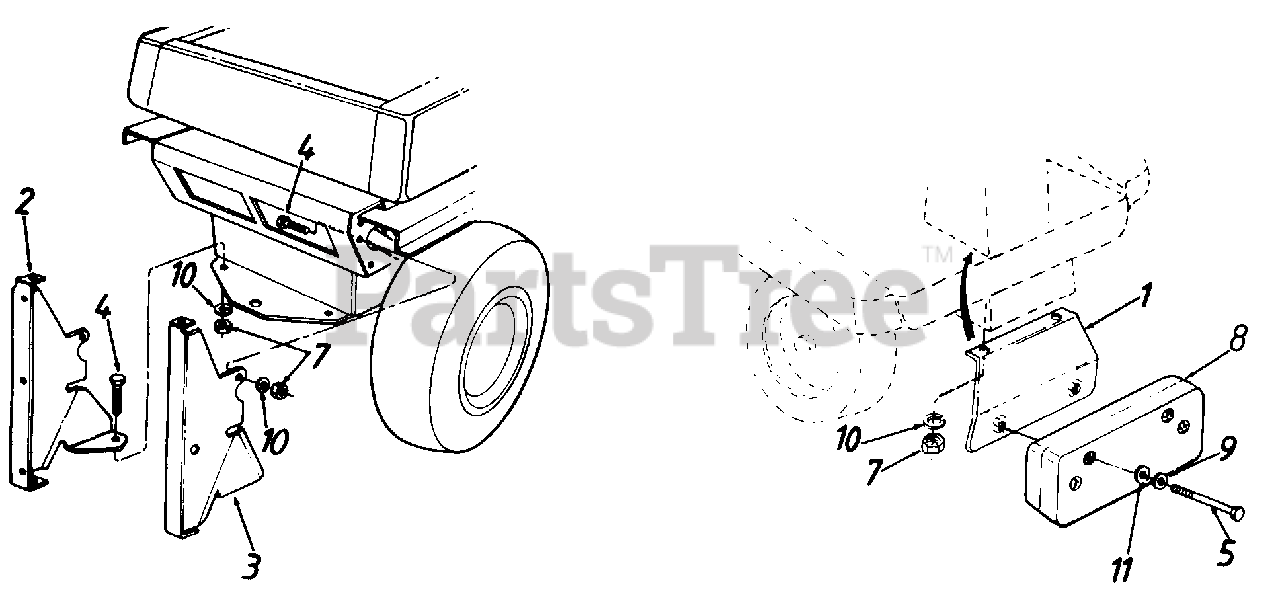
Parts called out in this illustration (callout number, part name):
1	Counterweight Support Brkt.
2	Catcher Support 8rkt.-R.H.
3	Catcher Support Brkt.-L.H.
4	Hex Bolt 5/16-18 x 1.0" Lg.
5	Hex Bolt 3/8-16 x 4.5" Lg.
7	Hex Nut 5/16-18 Thd.
8	Front Counterweight
9	Bell-Wash. 3/8" l.D.
10	L-Wash. 5/16" l.D.
11	Fl-Wash. .390" l.D. x 1.12" O.D.
